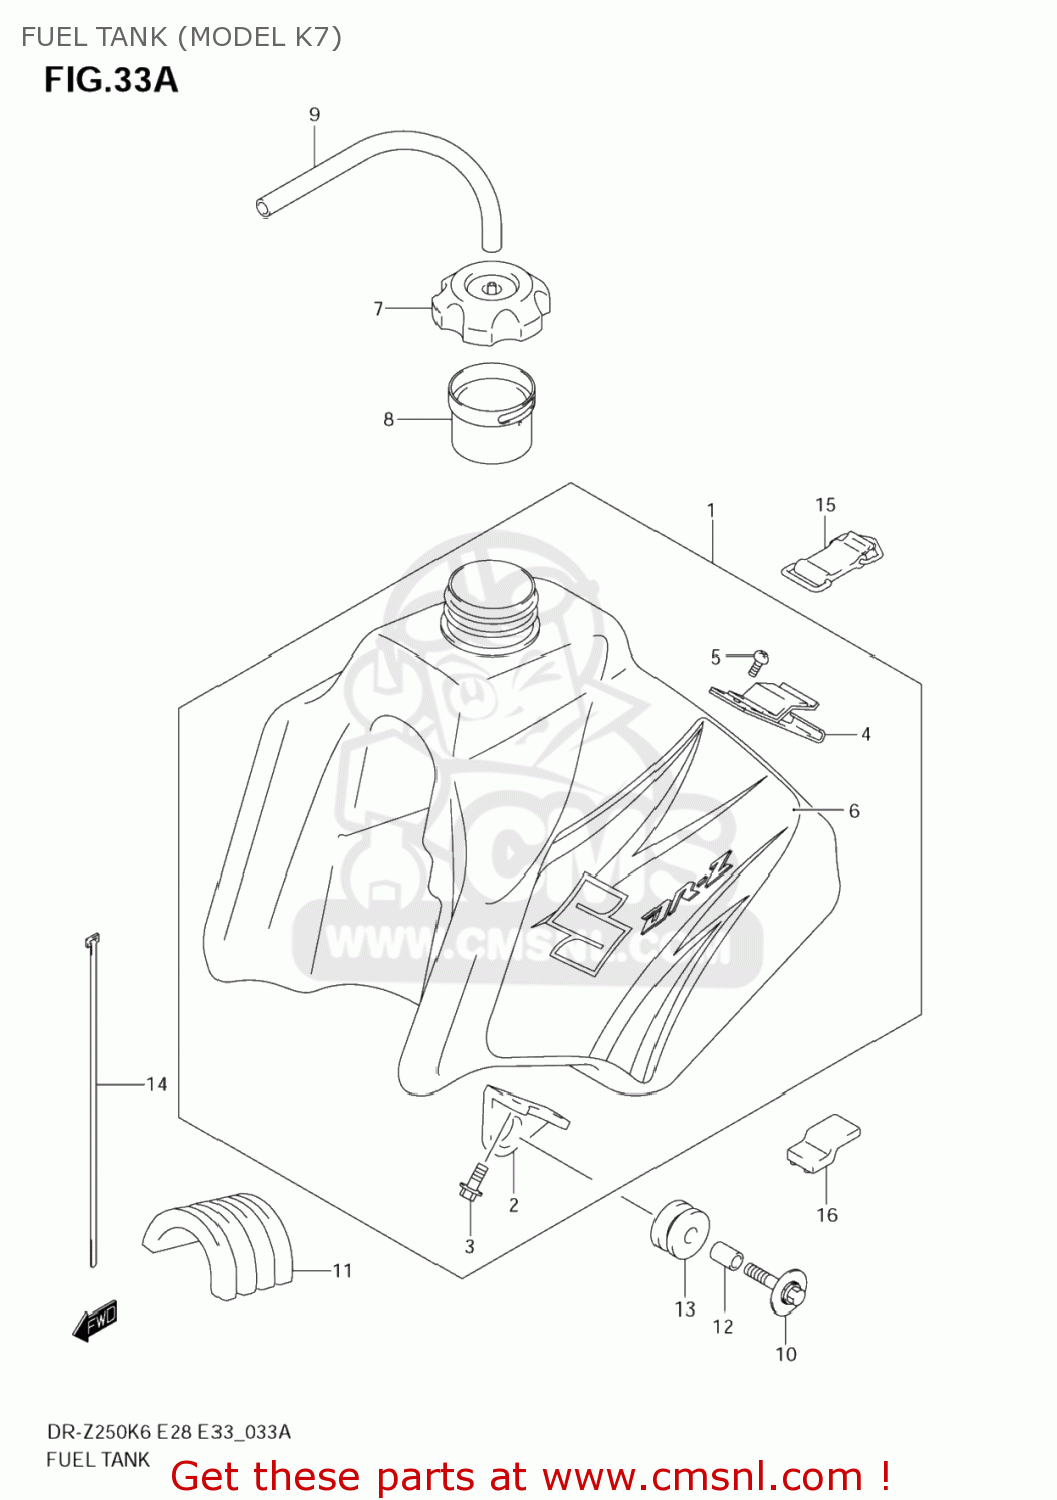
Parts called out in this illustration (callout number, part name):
1	TANK ASSY,FUEL(YELLOW)
2	BRACKET,FUEL TANK FR
3	BOLT
4	BRACKET,FUEL TANK RR
5	SCREW
6	TAPE SET,FUEL TANK
7	CAP ASSY,FUEL TANK FILLER
8	TUBE,FILLER INLET
9	HOSE(5X8.2X600)
10	BOLT(6X30)
11	CUSHION,FUEL TANK
12	SPACER(6.5X9X13.5)
13	CUSHION,MUFFLER
14	CLAMP(L:300)
15	BAND,FUEL TANK RR
16	CUSHION,FUEL TANK
